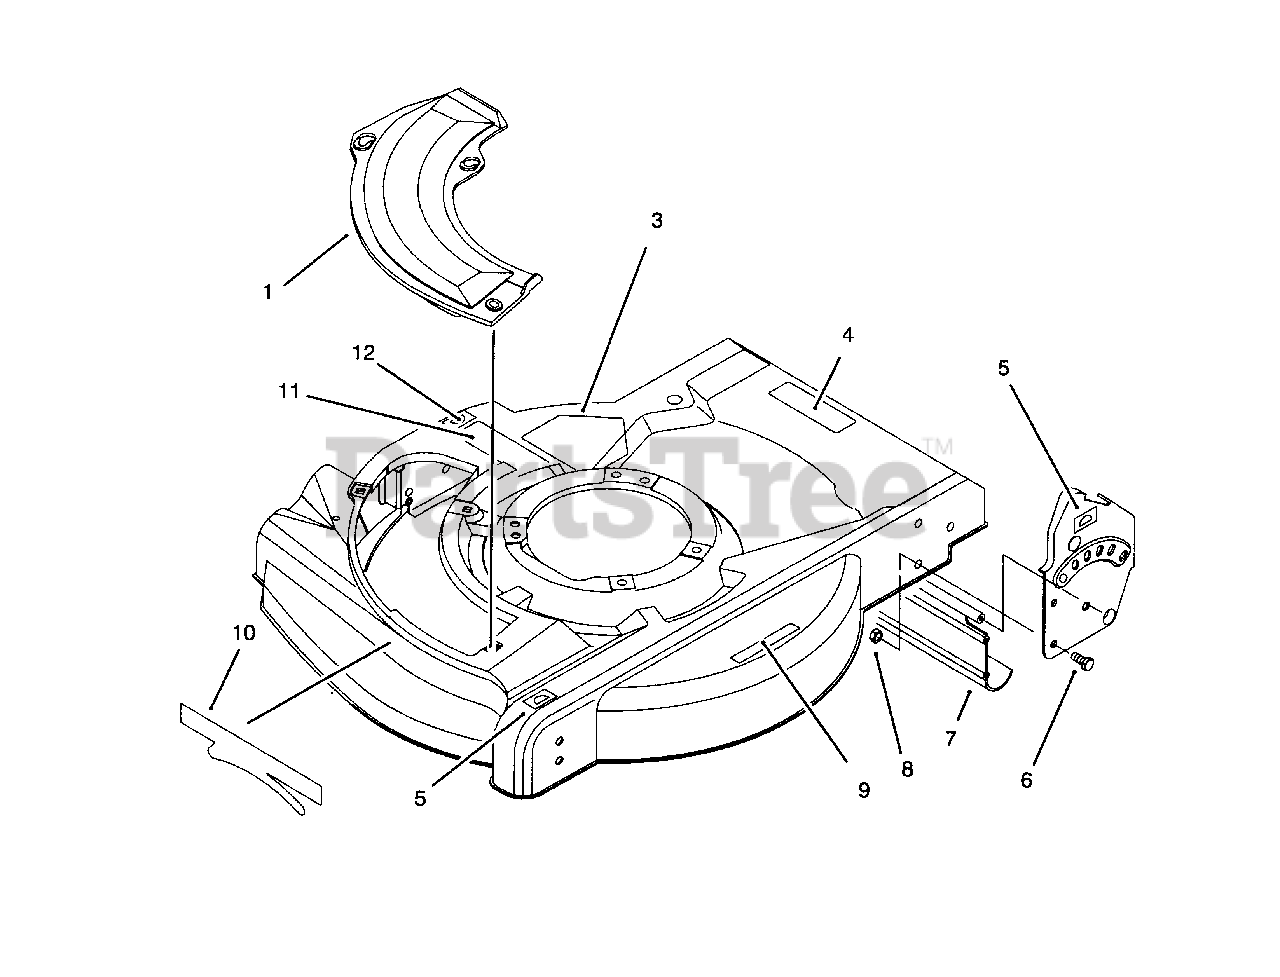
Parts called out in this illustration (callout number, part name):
1	Plate-Cover
3	Decal-Danger
4	Decal-Warning
5	Decal-H.O.C. L.H.
6	Screw-Hex Hd. Cap
7	Shield-Trailing
8	Nut-Lock
9	Decal-Warning
10	Decal-Deck
11	Decal-Discharge
12	Decal-H.O.C. R.H.
